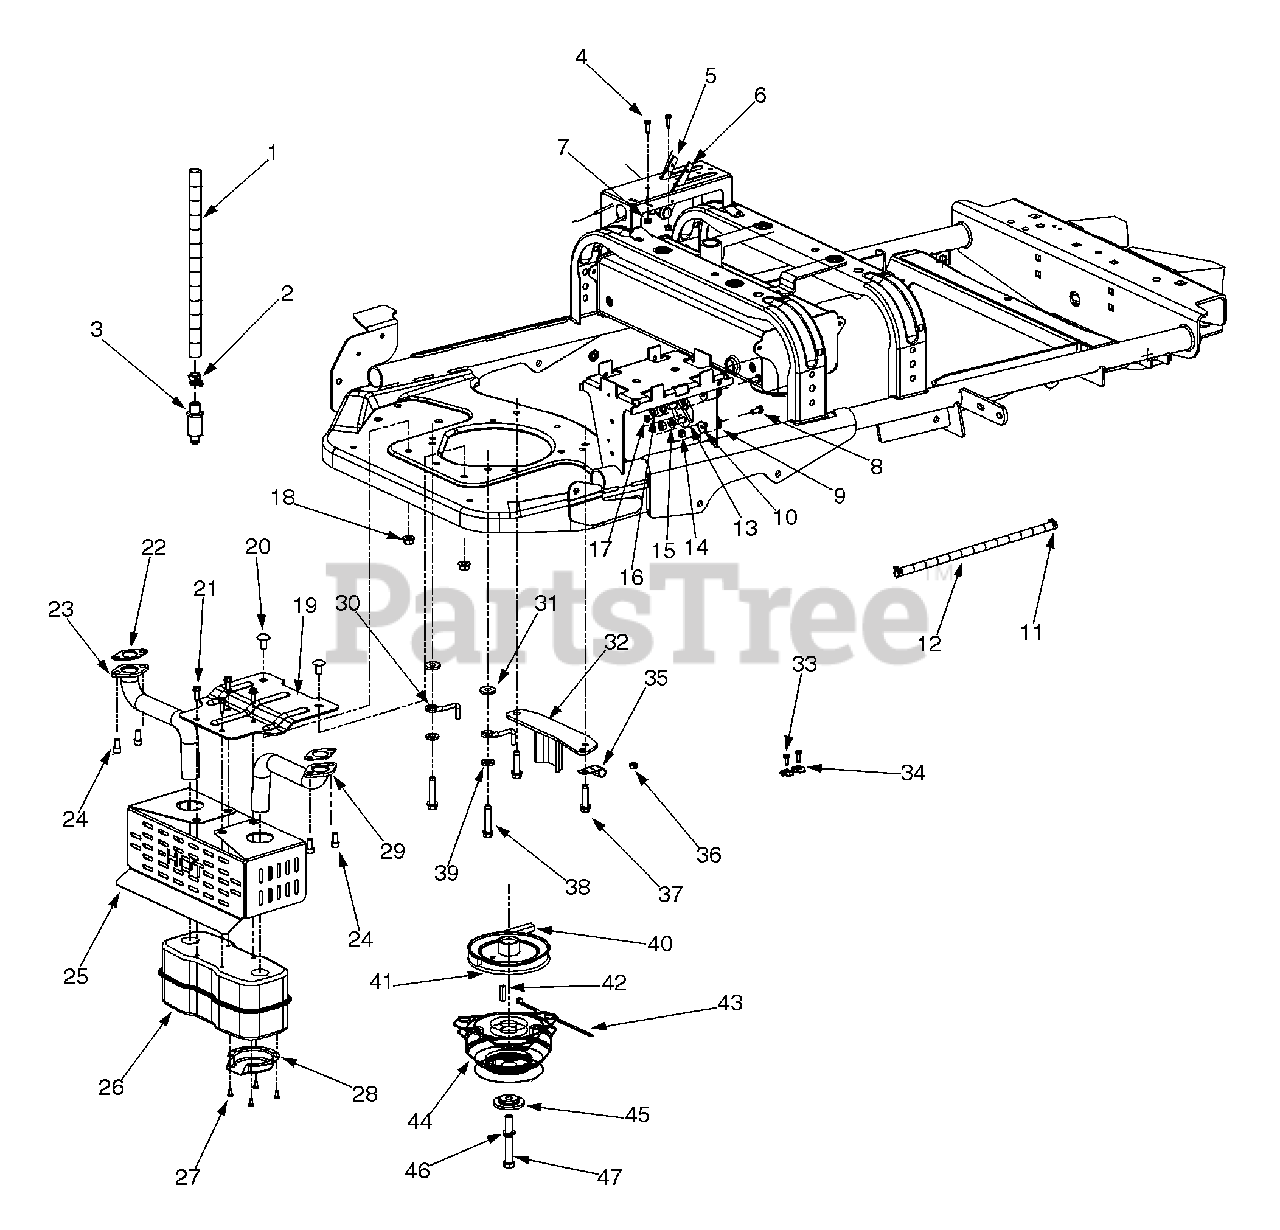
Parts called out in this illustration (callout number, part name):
1	Oil Drain Extension Hose
2	Oil Drain Cap
3	Oil Drain
4	Tap Screw #10-24 x .75
5	Throttle Cable
6	Choke Cable
7	Hex Lock Nut #10 - 24
8	Hex Cap Screw 1/4-20 x .620
9	Lock Washer 1/4 x 3/4
10	Bell Washer .265 x .75
11	Hose Clamp
12	Fuel Line Hose
13	Solenoid Switch
14	Hex Lock Nut 1/4-20
15	Lock Washer 5/16
16	Hex Nut 5/16-18
17	Hex Nut #10-32
18	Flange Lock Nut 3/8-16
19	Muffler Bracket
20	Carriage Bolt 3/8-16 x .75
21	Hex Washer Screw 1/4-20 x .75
22	Gasket
23	Exhaust Pipe - RH
24	Cap Screw 5/16-18 x .625
27	Hex Washer Screw #8-32 x .375
28	Muffler Deflector
29	Exhaust Pipe - LH
30	Rear Belt Retainer Rod
31	Flat Washer .385 x 1.0
34	Casing Clamp
35	Heat Shield Cable Clip
36	Hex Lock Nut 1/4-20
37	Hex Washer Screw 3/8-16 x 1.5
38	Hex Washer Screw 3/8-16 x 1.875
39	Flat Washer .407 x .812 x .135
40	V-Belt
41	Transmission Drive Pulley
42	Key 1/4 x 1.0
43	Cable Tie
44	Electric Clutch
45	Spacer Clutch
46	Lock Washer
47	Hex Cap Screw 7/16-20 x 3.25
